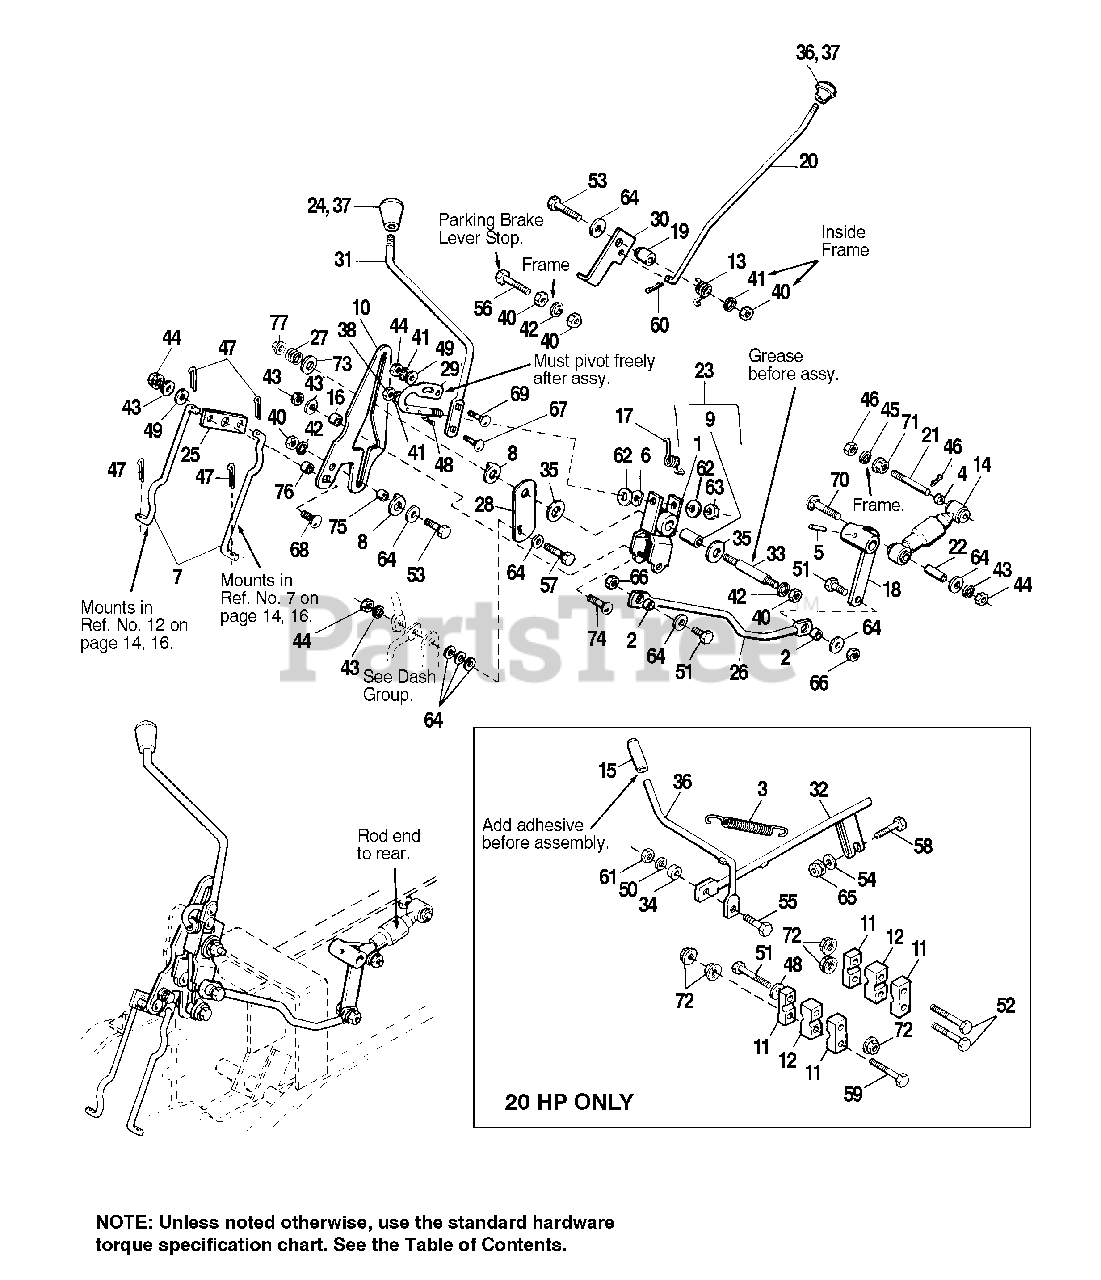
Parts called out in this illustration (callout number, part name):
2	SPACER, Ratchet Cage
3	SPRING
5	PIN, Spring, 1/4 x 1-1/4
6	WASHER, Curved, 1/2 x 1 x 1/64
7	ROD, Ground Speed Brake
8	WASHER, Lug
9	BEARING SLEEVE
10	CAM PLATE, Hydro Lever
11	BEARING HALF, Outer
12	BEARING HALF, Center
13	SPRING, Torsion
14	SHOCK ABSORBER
15	GRIP, Handle, Hi-Lo Control
16	SPACER, 21/64 x 5/8 x 1/2
17	SPRING, Torsion
18	LEVER ASSY, Control
19	SPACER, Parking Brake
20	ROD, Parking Brake
22	SPACER, 5/16
23	LEVER ASSY., Hyd. Control
24	KNOB, Hard Plastic
25	PLATE, Pivot
26	ROD, Hydro Control
27	SPRING, Compression
28	BRACE, Hydro Control
29	ROD, Hydro Control
30	LEVER, Parking Brake
31	LEVER, Shift Control
32	ROD ASSY., Hi-Lo Control, Lower
33	SHAFT, Pivot
34	SPACER
35	DISC., Friction
36	ROD, High-Low Control, Upper
37	KNOB, Shift Control, Soft
38	KNOB, Parking Brake, Soft
40	NUT, Hex, 3/8-16
41	LOCKWASHER, 1/4
42	LOCKWASHER, 3/8
43	LOCKWASHER, 5/16
44	NUT, Hex, 5/16
45	LOCKWASHER, 7/16
46	NUT, Hex, 7/16-14
47	PIN, Cotter, 3/32 x 3/4
48	PIN, Cotter, 1/8 x 3/4
49	WASHER, Plain,11/32 x 3/4 x 1/16
50	WASHER
51	CAPSCREW, Hex Hd., 3/8-16 x 1-1/4
52	CAPSCREW, Hex Hd., 5/16- 18 x 2-1/4
53	CAPSCREW, Hex Hd., 3/8-16 x 7/8
54	WASHER, Plain, 17/64 x 5/8 x 3/4
55	CAPSCREW, Hex Hd., 5/16-18 x 1
56	CAPSCREW, Hex Hd., 3/8-16 x 1-3/4
57	CAPSCREW, Hex Hd., 5/16-18 x 1-3/4
58	CAPSCREW, Hex Hd., 1/4-20 x 1-1/2
59	CAPSCREW, Hex Hd., 5/16-18 x 2-3/4
60	PIN, Cotter, 1/16 x 3/4
61	NUT, Hex Lock, 5/16-18
62	WASHER, Plain, 1/2 x 1-1/4 x 5/64
63	NUT, Hex, Centerlock, Jam, 1/2-13
64	WASHER, Plain, 13/32 x 7/8 x 5/64
65	LOCKNUT, Hex, Flange, 1/4-20
66	NUT, Hex, Centerlock, 3/8-16
67	CARRIAGE BOLT, 1/4-20 x 1-1/4
68	CARRIAGE BOLT, 5/16-18 x 7/8, Gr. 5
69	CARRIAGE BOLT, 5/16-18 x 1
70	CARRIAGE BOLT, 5/16-18 x 1-3/4
71	NUT, Hex, Flange, Whizlock, 7/16-14
72	LOCKNUT, Hex, Flange, 5/16-18
73	WASHER, Plain, 21/32
74	CARRIAGE BOLT, 5/16-18 x 1-1/4
75	SPACER, 25/64 x 5/8 x 13/32
76	SPACER, 5/16 x 5/8 x 7/32
77	LOCKNUT, Hex, Flange, 3/8-16
